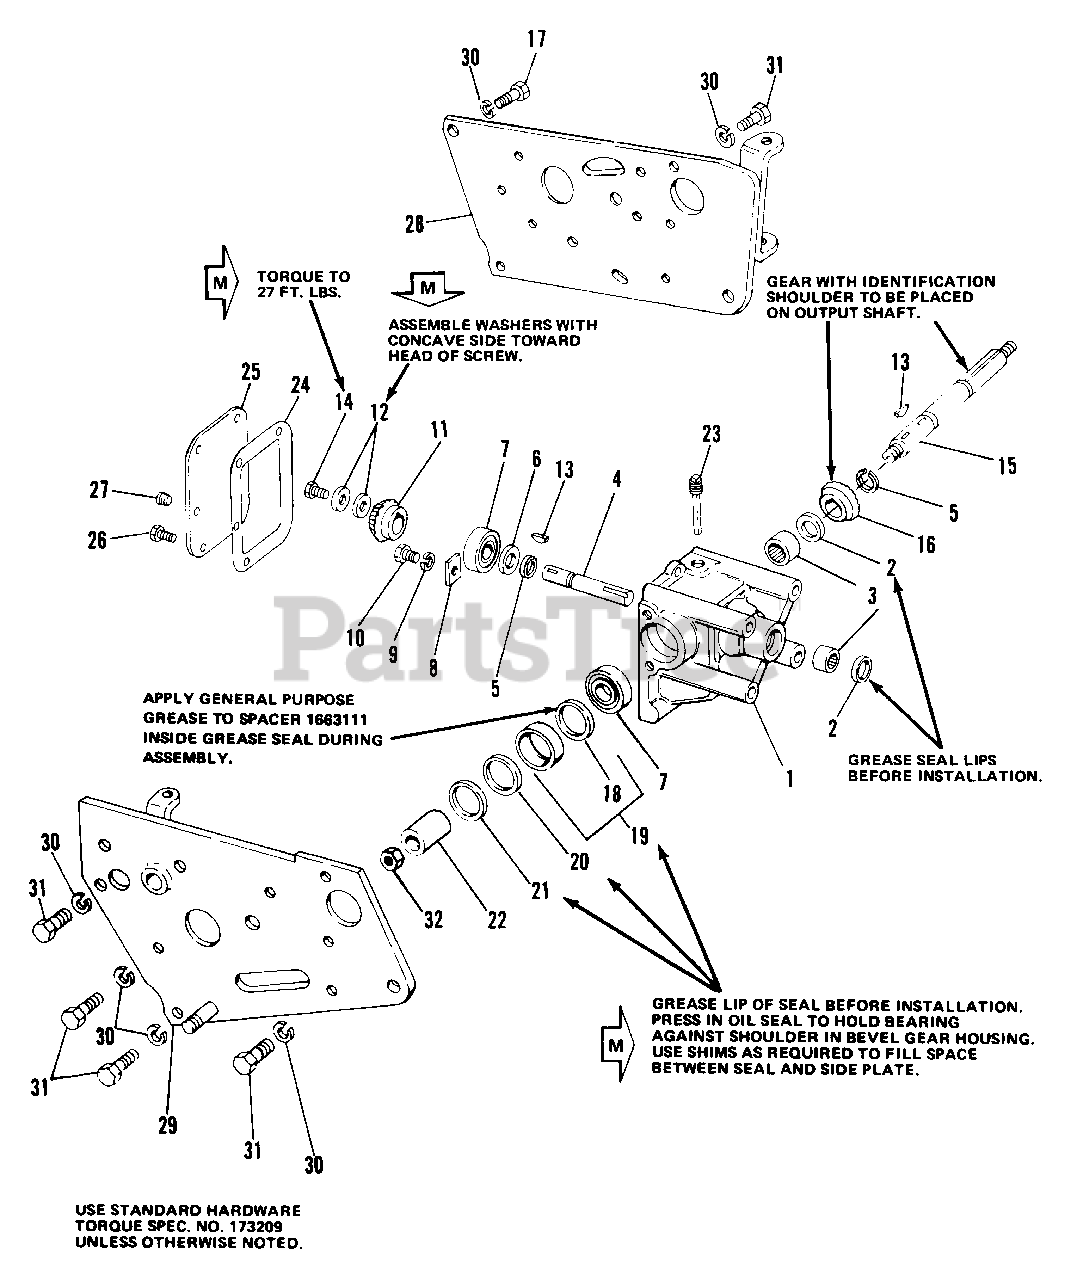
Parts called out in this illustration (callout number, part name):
1	HOUSING, Bevel Gear
3	BEARING, Needle
4	SHAFT, Driver
5	RING, Retaining
7	BEARING, Ball
8	PLATE, Bearing Clamp
9	LOCKWASHER, 5/16
10	CAPSCREW, Hex Hd., 5/16-18 x 5/8
11	GEAR, Bevel Driver
13	KEY, Woodruff, No. 9
14	CAPSCREW, Hex Hd., 5/16-18 x 3/4
15	SHAFT, Driven
16	GEAR, Bevel Driven
17	CAPSCREW, Hex Hd., 7/16-14 x 1-1/4
18	SPACER, Oil Seal
26	CAPSCREW, Hex, 1/4-20 x 5/8
28	PLATE ASSY, Side, L.H.
29	PLATE ASSY, Side, R.H.
30	LOCKWASHER, 7/16
31	CAPSCREW, Hex Hd., 7/16-14 x 1
32	LOCKNUT, Hex, Jam, 3/4-16
